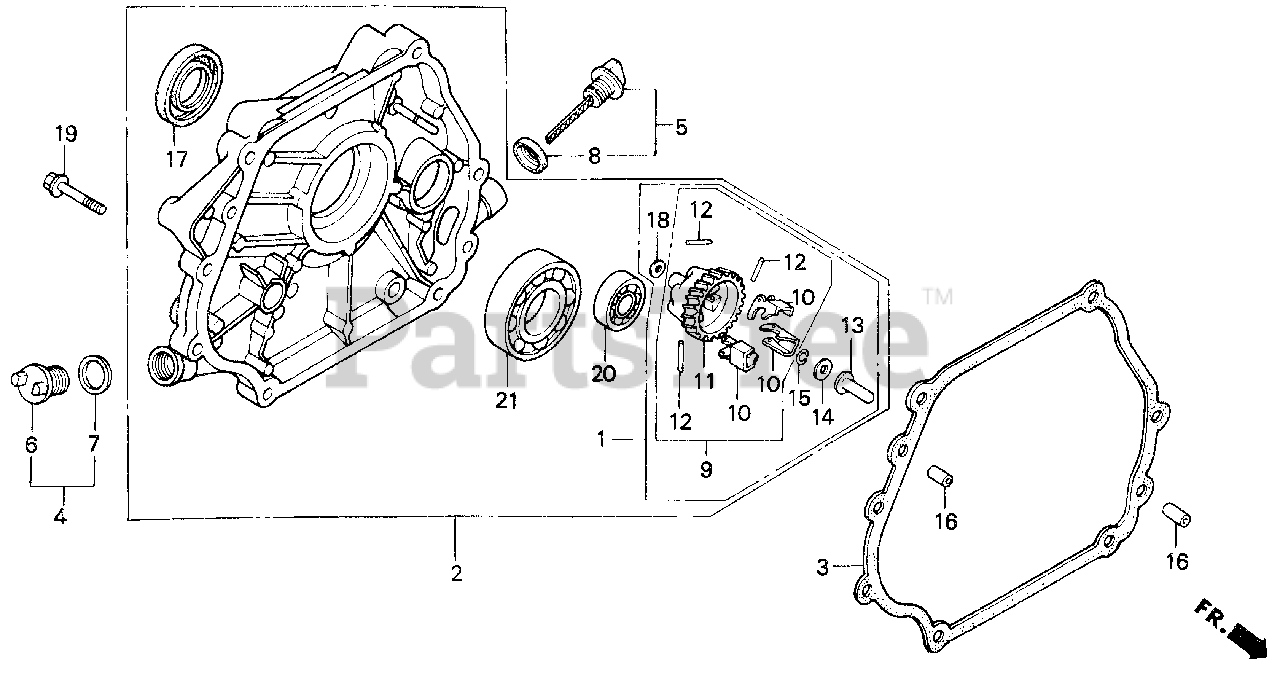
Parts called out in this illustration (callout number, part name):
1	GOVERNOR KIT
2	COVER ASSY., CRANKCASE (Q-TYPE)
3	GASKET, CASE COVER
4	CAP ASSY., OIL FILLER
5	CAP ASSY., OIL FILLER
7	GASKET, OIL FILLER CAP
8	GASKET, OIL FILLER CAP
9	GOVERNOR ASSY.
10	WEIGHT, GOVERNOR
11	HOLDER, GOVERNOR WEIGHT
12	PIN, GOVERNOR WEIGHT
13	SLIDER, GOVERNOR
15	CLIP, GOVERNOR HOLDER
16	PIN, DOWEL (8X12)
17	OIL SEAL (35X52X8)
18	WASHER, PLAIN (6MM)
19	BOLT, FLANGE (8X40)
20	BEARING, RADIAL BALL (6202)
21	BEARING, RADIAL BALL (6207)
